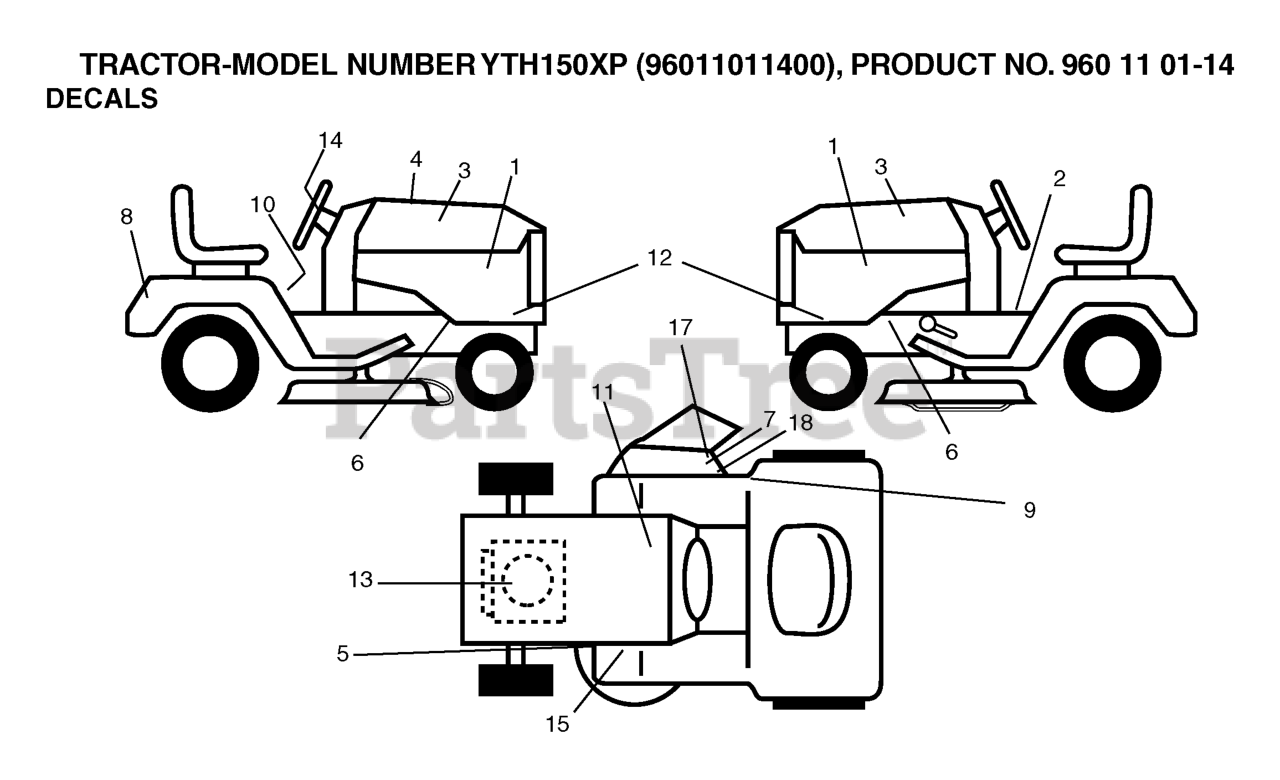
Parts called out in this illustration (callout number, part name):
1	DECAL.HOOD.HUSQVARNA.INTERNATI
2	DECAL PARK BRAKE
7	DECAL.INTERNATIONL.CUTFINGER
9	Decal, Fender 100 DB/CE
10	DECAL READ OWNER'S MAN SYMS
11	DECAL BTRY SYMBOLS
13	DECAL
14	DECAL.STEERING.HUSQ.BLUE
15	DECAL V BELT SCHEMATIC
17	DECAL DECK "B" 42"
18	DECAL
